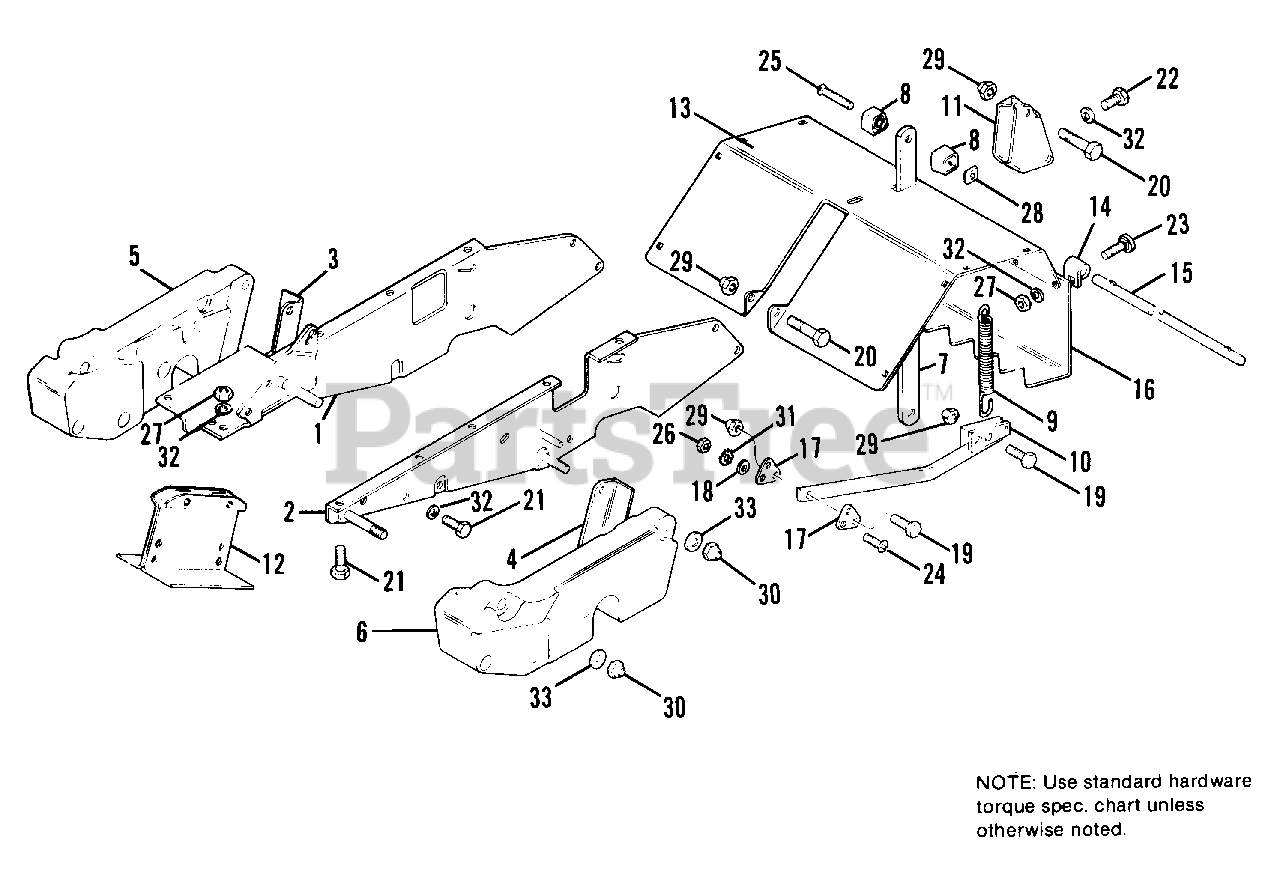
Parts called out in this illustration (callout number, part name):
1	FRAME ASSEMBLY-R.H.
2	FRAME ASSEMBLY-L.H.
3	HANGER-Rear R.H.
4	HANGER-Rear L.H.
5	COUNTERWEIGHT-R.H.
6	COUNTERWEIGHT-L.H.
7	DEPTH CONTROL ASSEMBLY
10	SKID ASSEMBLY
11	SUPPORT ASSEMBLY
12	SUPPORT ASSEMBLY-Counterweight
13	TINE SHIELD & DECAL ASSEMBLY
16	GUARD ASSEMBLY
19	CAP SCREW, Hex Hd. 5/16-18 x 1" Plated
20	CAP SCREW, Hex Hd. 5/16-18 x 2-1/4" Plated
21	CAP SCREW, Hex Hd. 5/16-18 x 5/8" Plated
22	CAP SCREW, Hex Hd. 5/16-18 x 1/2" Plated
23	BOLT, Carriage 5/16-18 x 3/4" Plated
24	MACHINE SCREW, Slotted Rd. Hd. #10-24 x 1" Plated
25	MACHINE SCREW, Slotted Flat Hd. 5/16-18 x 2" Plated
26	NUT, Hex #10-24 Plated
27	NUT, H7ex 5/16-18 Plated
28	NUT, Square 5/16-18 Plated
29	NUT, Hex Center Lock 5/16-18 Plated
30	NUT, Hex Center Lock 3/8-16 Plated
31	WASHER, Lock External Tooth #10 Plated
32	WASHER, Spring Lock 5/16 Plated
33	WASHER, Flat SAE 3/8 Plated
